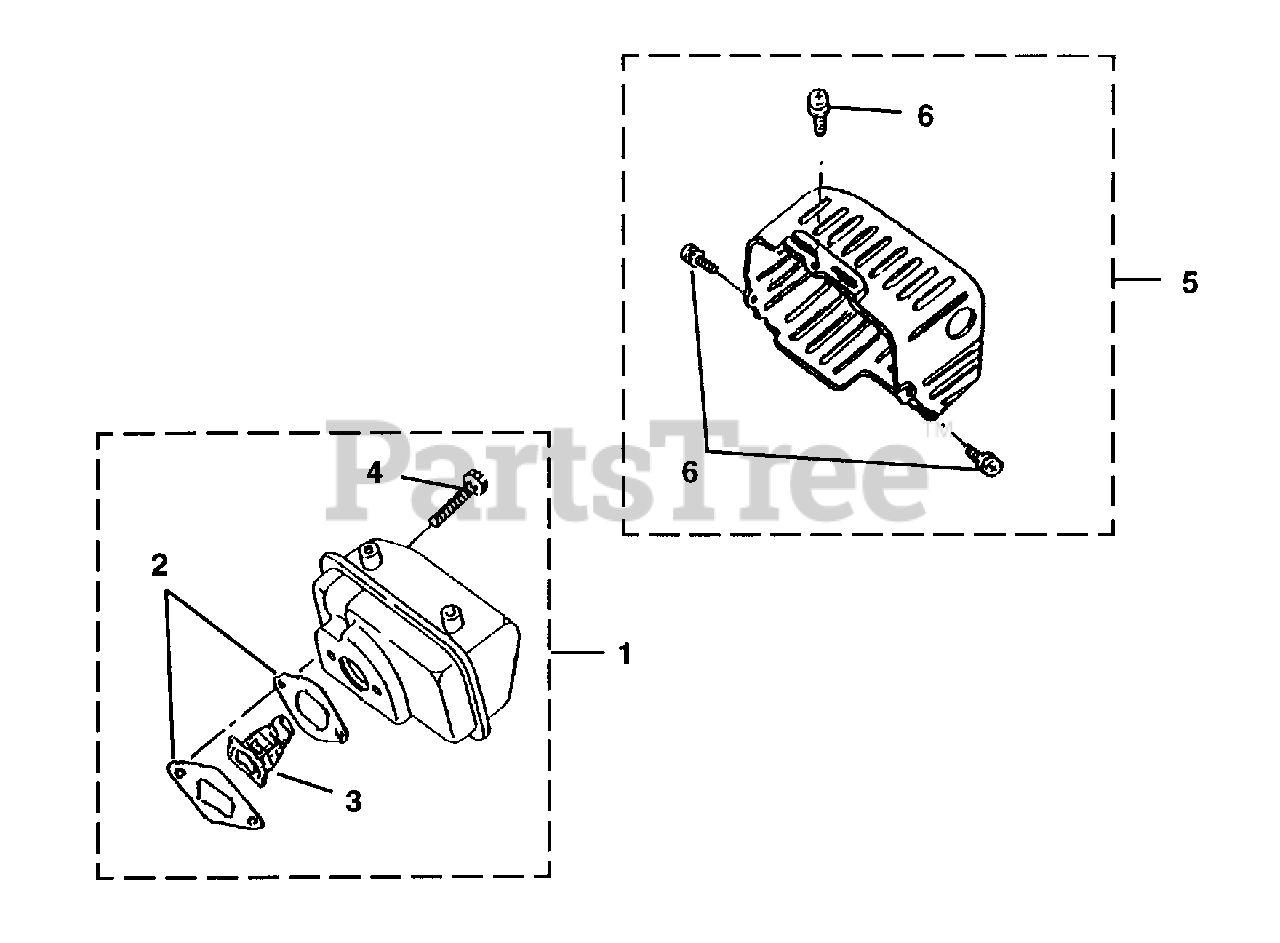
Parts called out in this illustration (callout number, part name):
1	MUFFLER ASSEMBLY
2	GASKET- Muffler
3	SPARK ARRESTER
4	SCREW-Socket Hd (M6 X 60 SW)
5	MUFFLER COVER
6	SCREW (M5 x 14 W SW)
